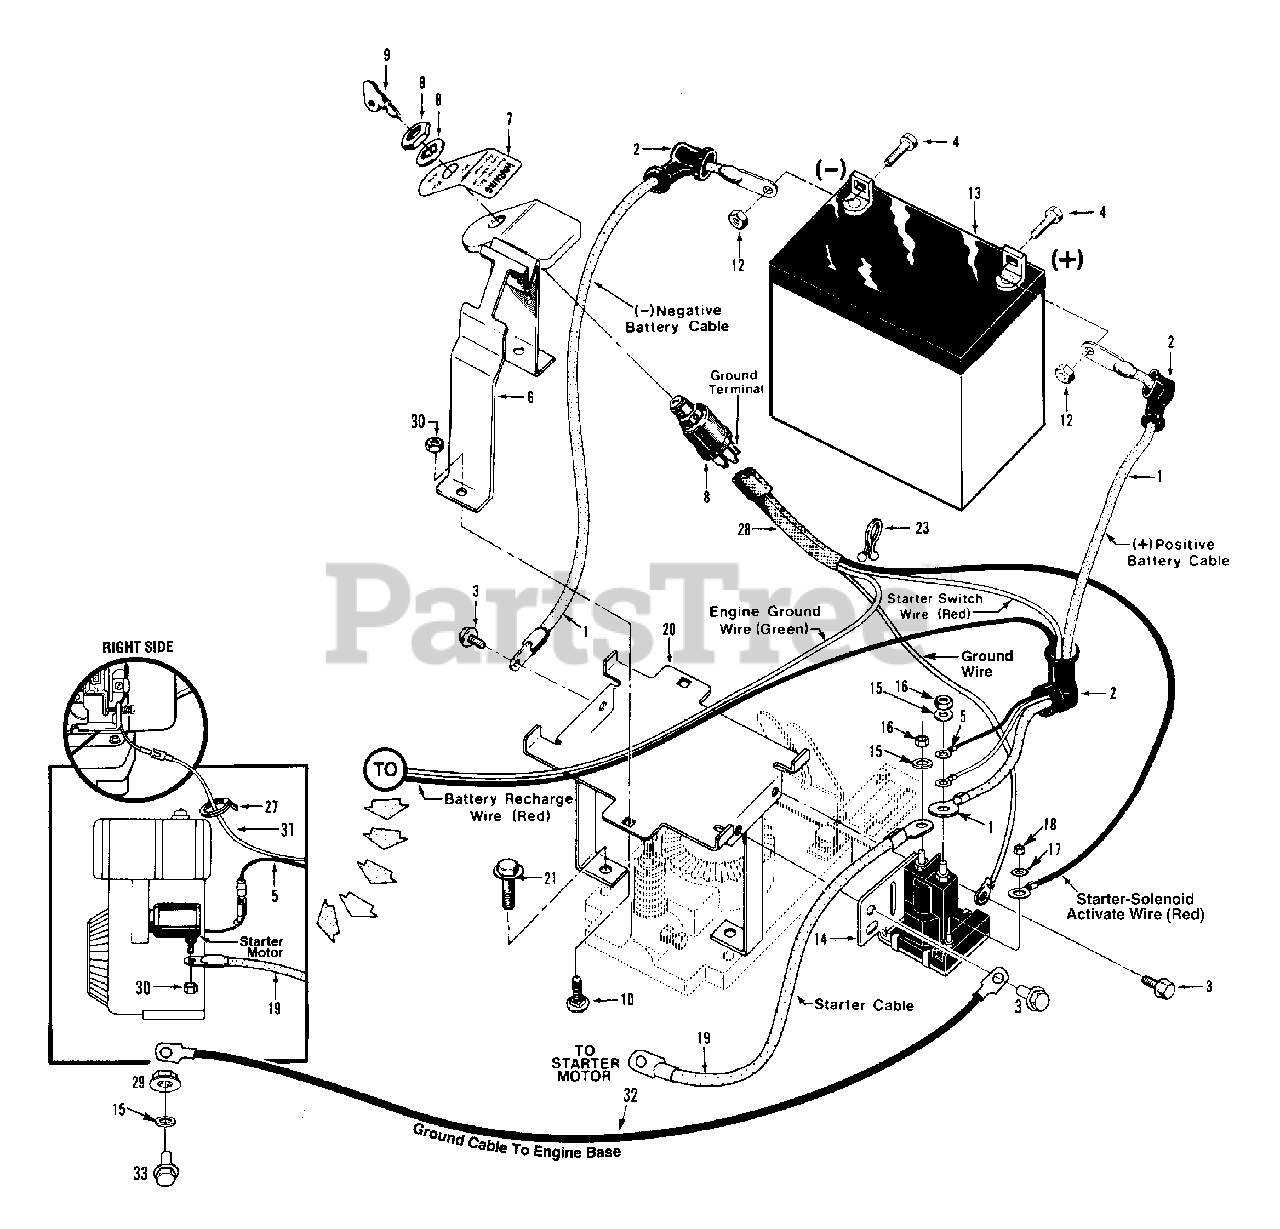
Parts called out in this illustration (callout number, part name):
1	Cable-battery, positive and negative terminals
2	Boot-terminal insulating
3	Screw-self-threading, 1/4-20 x 1/2"
4	Bolt-hex hd., 1/4-20 x 5/8"
5	Wire-recharge (red)
6	Battery Hold-down Clamp-with attached Key Switch Plate
7	Decal-ignition switch instruc
8	Key Switch
9	Key-ignition, one pair
10	Bolt-carriage, 1/4-20 x 1-1/4"
11	Lockwasher-spring lock, 1/4"
12	Nut-hex, 1/4"-20
13	Battery-12 volt, 270 CCA
14	Solenoid-starter
15	Lockwasher-5/16"
16	Nut-hex, 5/16"-24
17	Lockwasher-external tooth, #10
18	Nut-hex, #10-32,
19	Cable-solenoid to starter motor
20	Battery Bracket
21	Bolt-flanged hex hd., 3/8-16 x 1-1/2"
23	Tie-plastic, wire retaining
27	Tie-plastic
28	Wire Harness & Connecting Terminal Assembly
29	Nut-flange lock, 5/16"-18
30	Locknut-hex, 1/4"-20
31	Ground Wire Assembly
32	Cable-ground, solenoid to engine block
33	Bolt-flange lock, 5/16-18 x 1"
